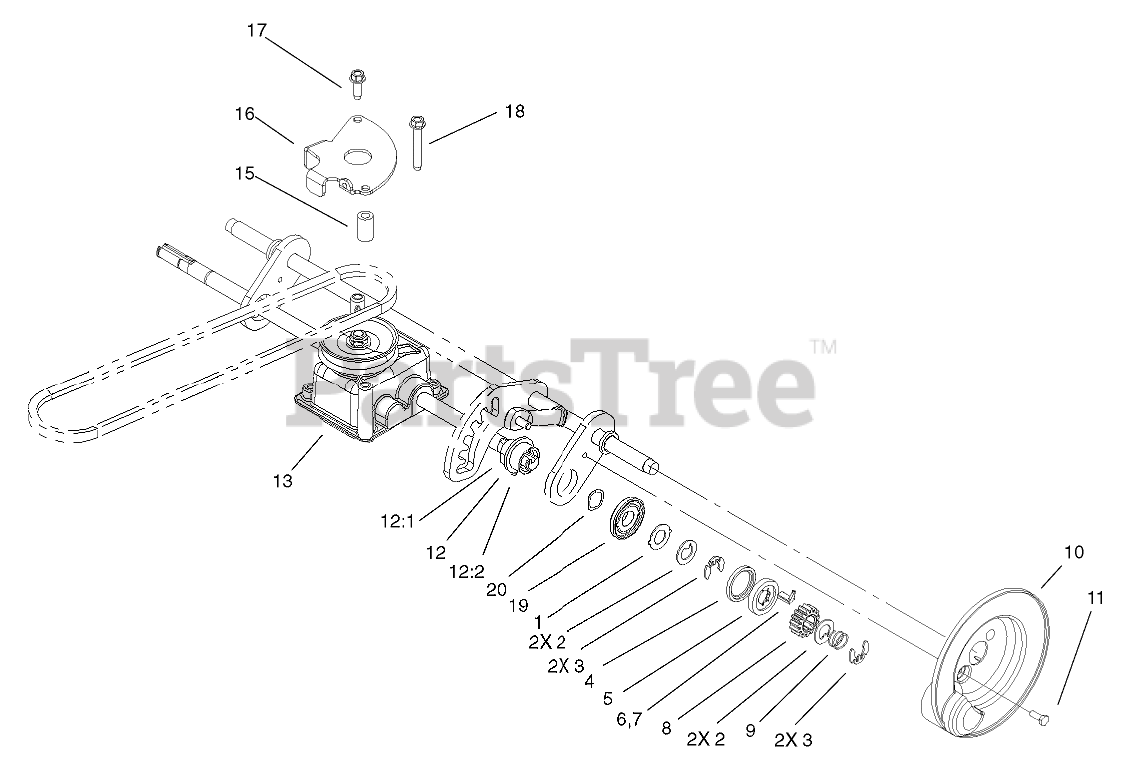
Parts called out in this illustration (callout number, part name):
1	WASHER-ARM, PIVOT
2	WASHER-THRUST, KEYED
3	RING-CLIP, LOCKING
4	RING-FRICTION
5	WASHER-CLUTCH
6	KEY-ROCKING, RH
7	KEY-ROCKING, LH
8	GEAR-PINION
9	SPRING-COMPRESSION
10	COVER-GEAR
11	SCREW-TAPTITE
12	BUSHING ASM
12:1	BUSHING
12:2	FITTING-GREASE
13	GEAR CASE ASM
15	BUSHING-PLATE, ACTUATOR
16	GUIDE-TRANSMISSION
17	SCREW-HWHTF
18	SCREW-HWHTF
19	RETAINER-RING
20	WASHER-WAVE
